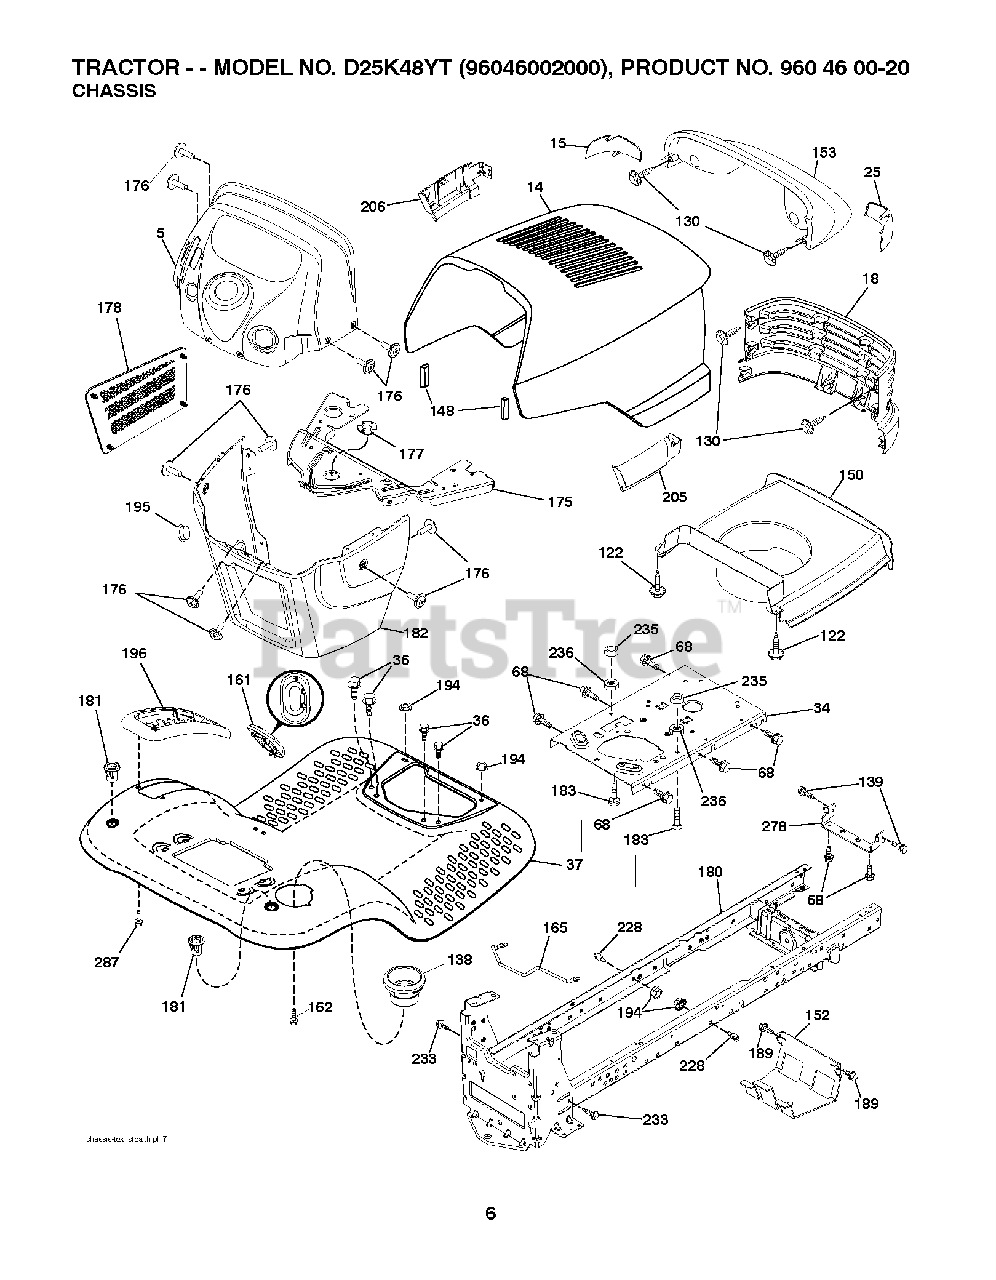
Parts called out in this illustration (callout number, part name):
5	DASH.UPR.STEALTH.BLACK
14	HOOD.ASM.DIXON.STEATH.SRS.BLUE
15	LENS LH
18	GRILLE.STEALTH.GT.BLACK
25	LENS RH
34	PLATE.ENGINE.WELDED.CHASSIS
36	SCREW 5/16"
37	FENDER.TLT.W/CPH.W/FW.666
68	SCREW LT
122	SCREW.WSHD.HEX10-32X5/8
130	SCREW.#10 X 0.750.BOS (2 2)
138	CUPHOLDER.TL.TEX.BLACK
139	BOLT, SHOULDER 5/16-18
148	EXTRUSION BUMPER
150	DUCT.HEAT.HOOD.STEALTH.GT
152	SHIELD.BROWNING.W/TEX
153	LIGHTBOX.ASM.STEALTH.DL.DIXON
161	WINDOW.FUEL.LT.TEX.BLACK
162	SCREW.HI-LO.CONSOLE
165	SUPPORT.TANK.REAR.W/TEX
175	CROSSMEMBER.
176	SCREW.#10-24X5/8.RN.QU
177	BUSHING,STEERING
178	CARGO.ASM.NET.DASH.LOWER
180	CHASSIS
181	FEND/FTRST.PCH.CPH.NFW
182	DASH.LOWER.
183	BOLT.5/16-18X1-1/4 FULL THD
189	SCREW
194	NUT LOCK HEX FLANGE 5/16-18
195	PLUG.HOLE.DASH.
196	CONSOLE.ASM.DECKLFT.BL/RBT.TLT
205	SKIRT.GRILLE.STEALTH.RH
206	SKIRT.GRILLE.STEALTH.LH
228	STUD.FASTNER.W/ANTI-ROTATE
233	BOLT.SHOULDER
235	SPACER FENDER
236	NUT.CENTERLOCK.5/16-
278	BRKT.HOOD/MUFF.STEALTH
287	SCREW 1/4X20
